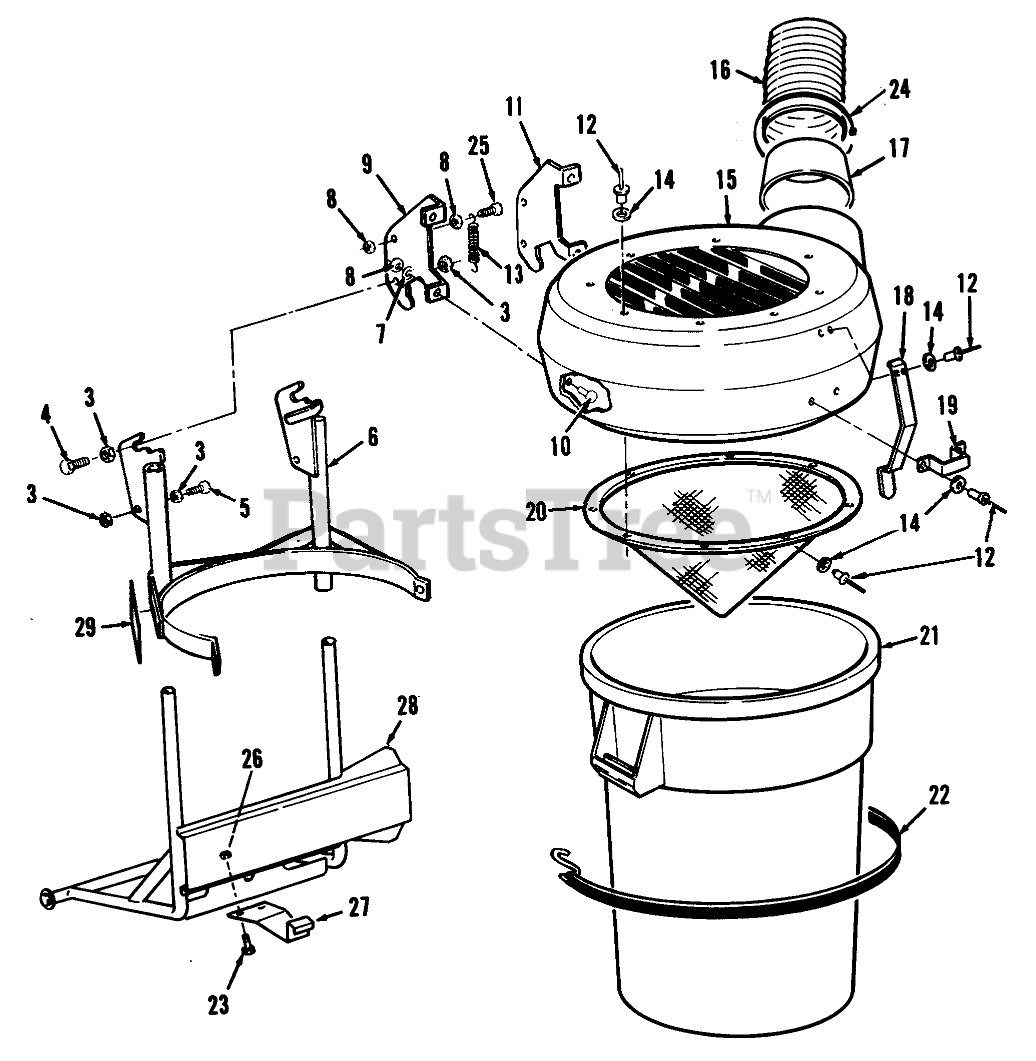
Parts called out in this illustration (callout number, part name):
3	NUT-HEX
4	SCREW-HH
5	SCREW-HH
6	Support-Canister
7	WASHER-PLAIN
8	NUT-LOCK, NI
9	LH TOP BRACKET B
10	SCREW-HH
11	RH TOP BRACKET B
12	RIVET-POP
13	SPRING-EXTENSION
14	Washer
15	TOP-CANISTER
16	HOSE 6" X 48"
17	SEAL ASSEMBLY NP
18	LATCH-BAGGER TOP B
19	BRACKET B
20	SCREEN-BAGGER TOP
21	CANISTER
22	STRAP B
23	SCREW-HH
25	SCREW-HH
26	NUT-HEX
27	BRKT-CANISTER SUP B
28	WLDMT-BAGGER RODS B
29	DECAL-DANGER
